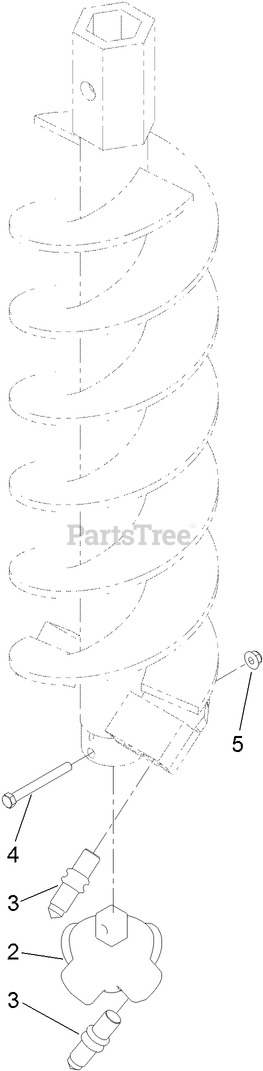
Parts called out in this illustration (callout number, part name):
2	PILOT-AUGER, ROCK
3	TOOTH-BULLET
4	SCREW-HH
5	NUT-HF, NI
